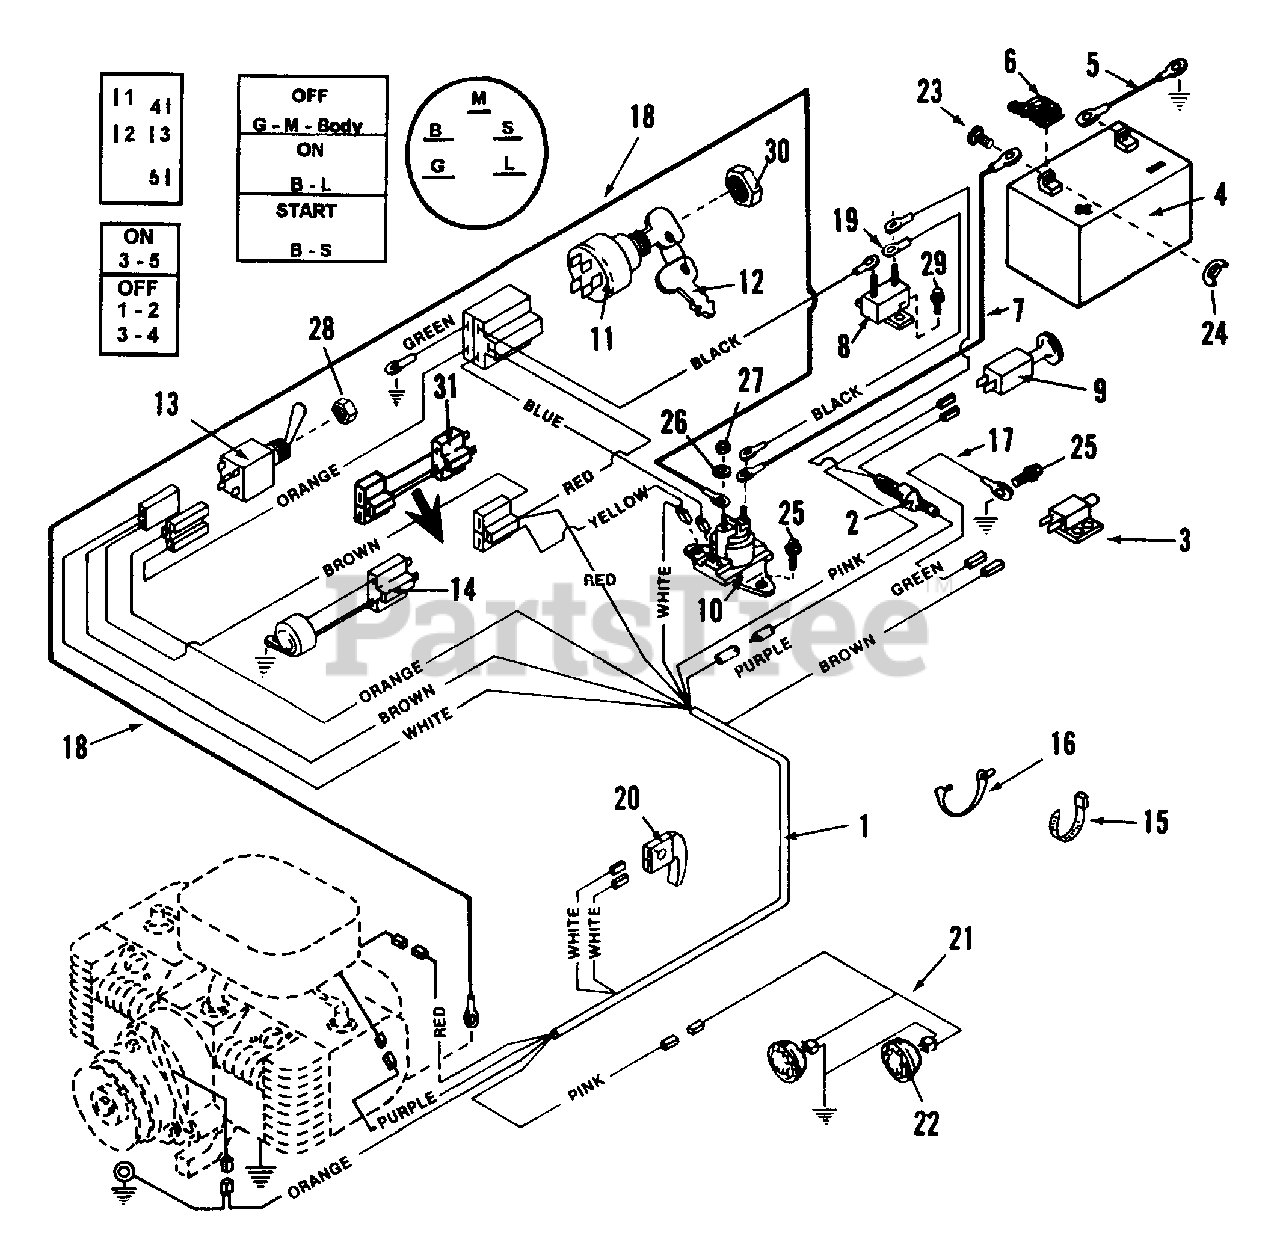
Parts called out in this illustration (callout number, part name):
1	HARNESS, Wiring
2	HARNESS, Diode
3	SWITCH, Seat Interlock (NO)
4	BATTERY 12V 30 Amp Hour
5	CABLE, Negative (Black)
6	COVER, Positive Terminal
7	CABLE, Solenoid/Starter (11")
8	CIRCUIT-BREAKER
9	SWITCH, Headlamp
10	SOLENOID
11	KEYSWITCH
12	KEY
13	SWITCH, PTO
14	MODULE, Interlock - B&S
15	TIE, Wire
16	TIE, Cable
17	WIRE, Seat Switch to Ground
18	CABLE, Solenoid/Starter (36")
19	WIRE, Breaker to Solenoid
20	SWITCH, Clutch Interlock
21	HARNESS, Headlamp
22	HEAD-LAMP
23	BOLT, 1/4-20 X 3/4" Carriage
24	WING-NUT, 1/4-20
25	SCREW, 1/4-20 X 5/8" Hex Washer Self-Tap
26	WASHER, 1/4 Int.Tooth Lock
27	NUT, 1/4-20 Hex
28	NUT, Special 1/2-27 Hex
29	SCREW, #10-24 x 1/2" Hex Washer Self-Tap (Torx)
30	NUT, Special 5/8-32 Hex
31	HARNESS, Module Repair (NLA)
